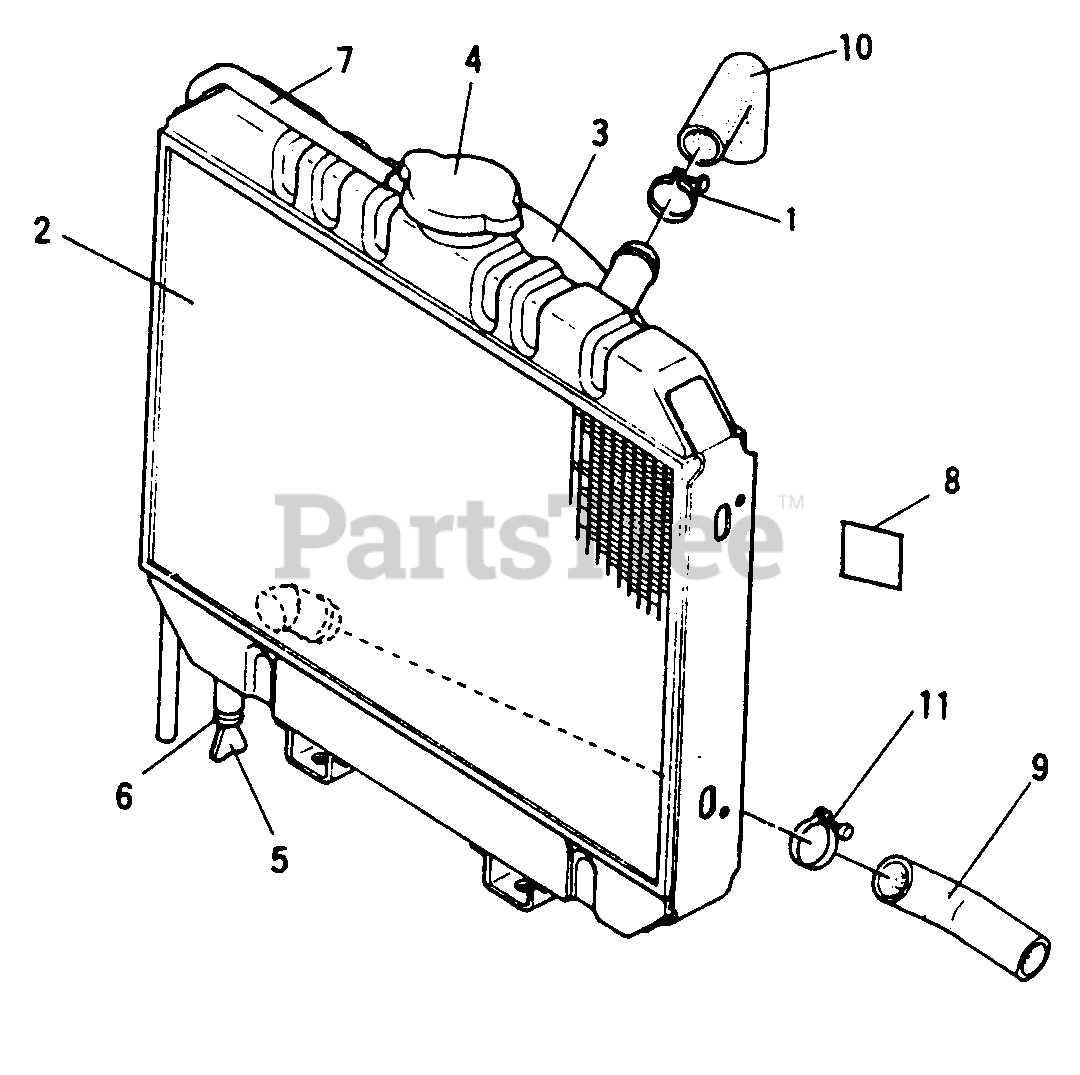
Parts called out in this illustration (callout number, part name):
1	Clamp, No. 20 Type F Hose
2	Radiator
4	Cap, Radiator
7	Tube, Overflow
8	Label, Radiator
9	Hose, Lower Water
10	Hose, Upper Water
